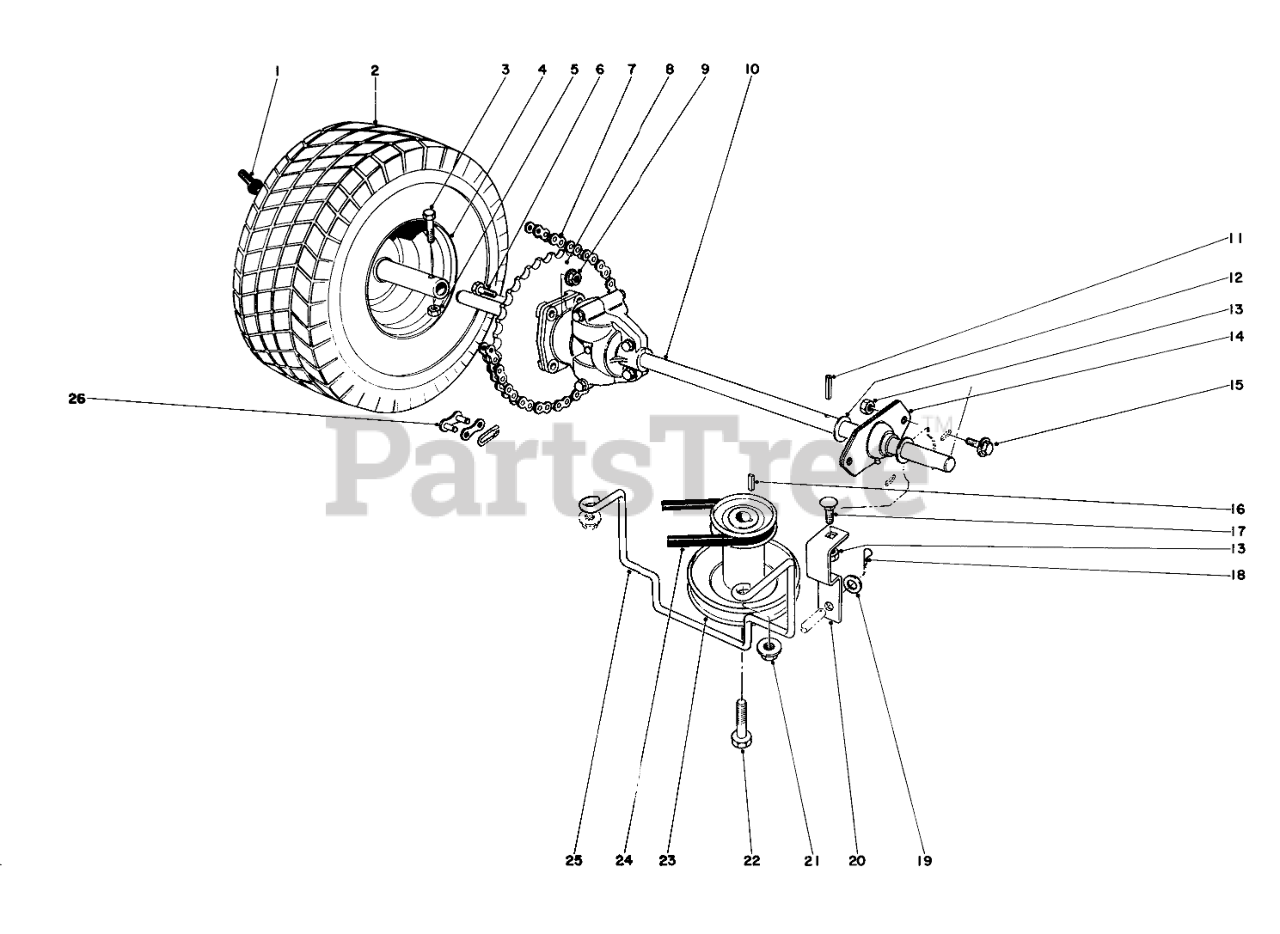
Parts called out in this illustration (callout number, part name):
1	STEM-VALVE
2	Tire Turf King
3	SCREW-HH
5	NUT-LOCK, CONE
6	SCREW-HH
7	Chain
8	Differential Sprocket
9	Locknut
10	Differential Ass-y.
11	PIN-ROLL, SLOTTED
12	Washer
13	NUT-LOCK, CONE
14	Rear Axle Bearing
15	SCREW-HHF
16	KEY-SQUARE
17	SCREW-CARR
18	PIN-COTTER
19	WASHER-PLAIN
20	Bracket
21	NUT-HF
22	SCREW-HH
23	Pulley
24	V-BELT
25	Belt Retainer
26	LINK-CONNECTING
